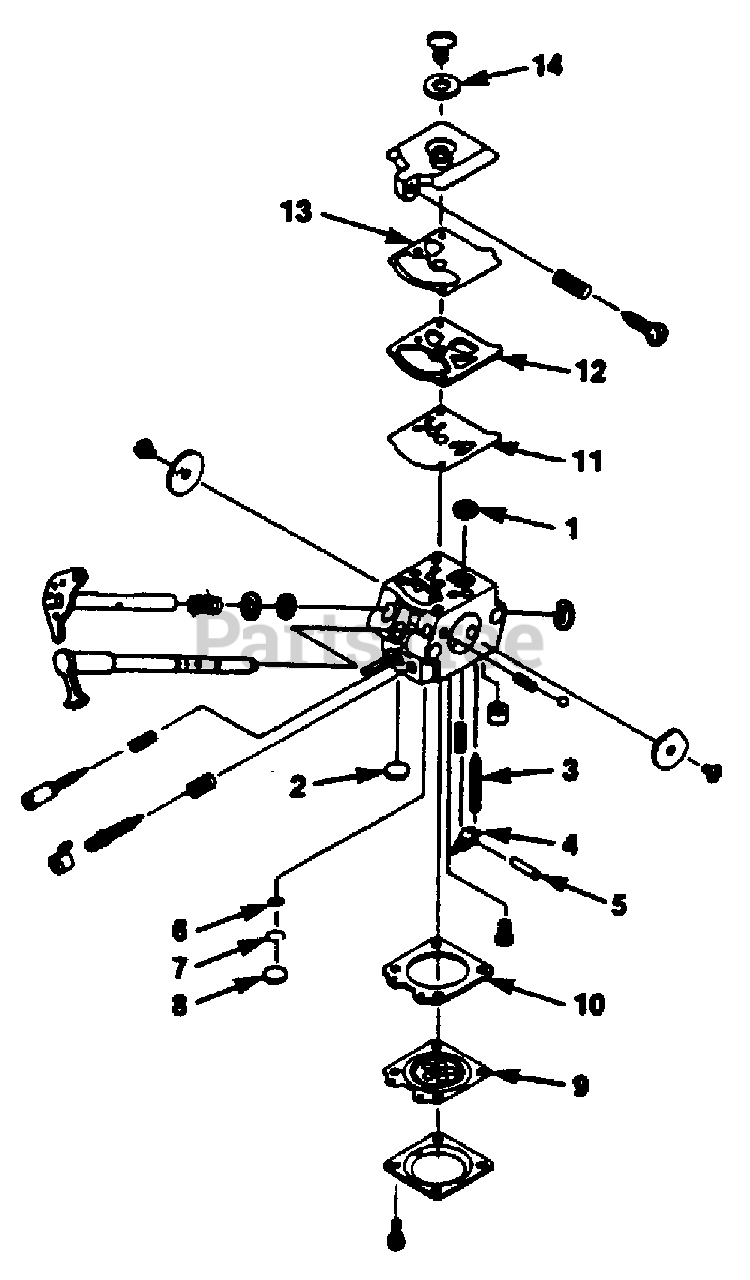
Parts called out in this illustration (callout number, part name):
1	Repair Kit
2	Repair Kit
3	Repair Kit
4	Repair Kit
5	Repair Kit
6	Repair Kit
7	Repair Kit
8	Repair Kit
9	Repair Kit
10	Repair Kit
11	Repair Kit
12	Repair Kit
13	Repair Kit
14	Repair Kit
